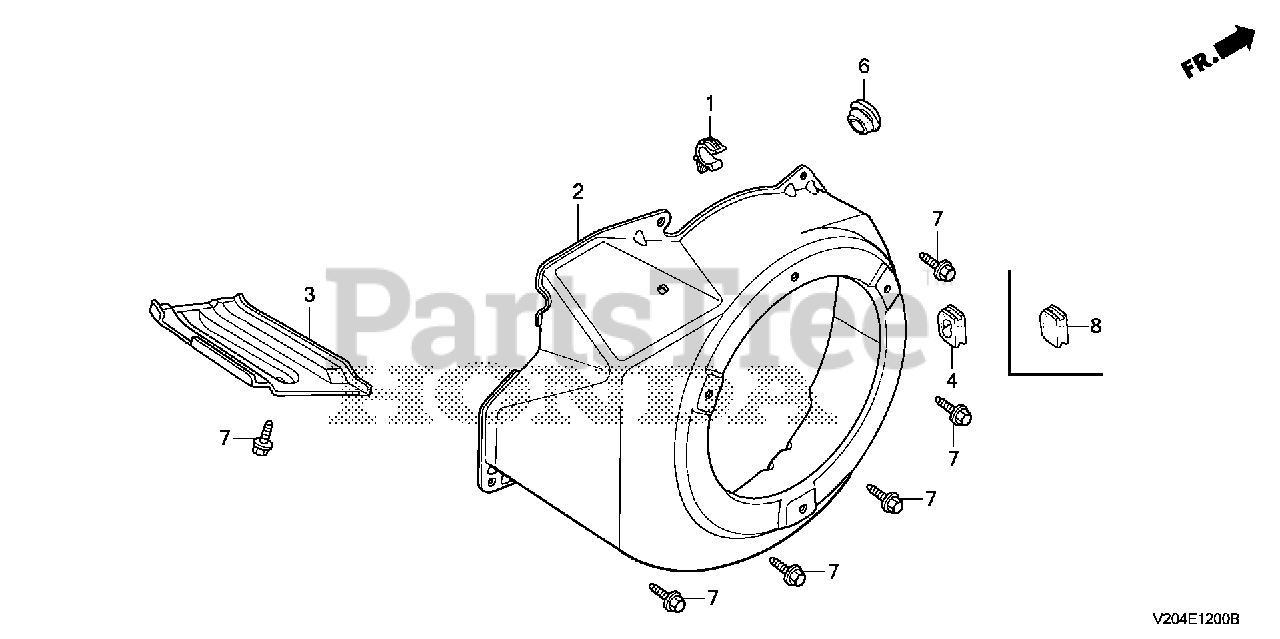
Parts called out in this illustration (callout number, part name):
1	CLIP, TUBE
2	COVER, FAN *R280* (Honda Code 7323561). (POWER RED)
3	SHROUD
4	GROMMET, WIRE
6	GROMMET, DRAIN HOLE
7	BOLT, FLANGE (6X12) (CT200)
